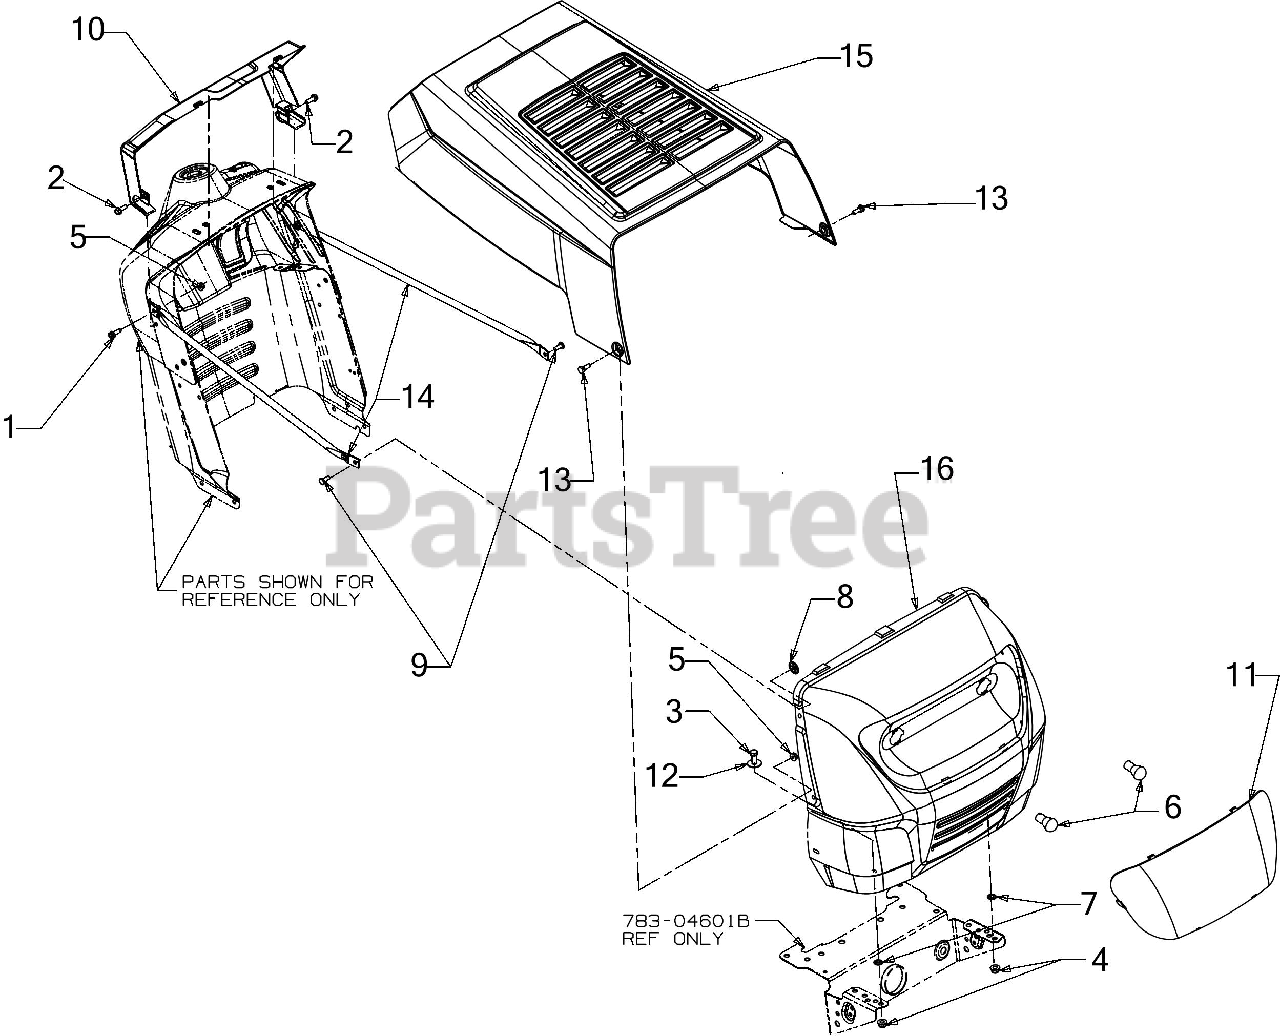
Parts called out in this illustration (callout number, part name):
1	SCREW 1/4-20 x .750
2	SCREW 1/4-15 x .750
3	SCREW 5/16-18 x .75 GR5
4	FLANGE LOCK NUT 5/16-18
5	FLANGE LOCK NUT
6	MINIATUURE BULB 12V
7	PUSH NUT
8	PUSH ON NUT
9	FLAT HEAD RIVET
10	DASH COLLAR
11	LENS STYLE 2
12	FLAT WASHER 344X1.00
13	SHOULDER SCREW
14	GRILLE SUPPORT ROD
15	HOOD- 0 STYLE
16	GRILL-2 STYLE
